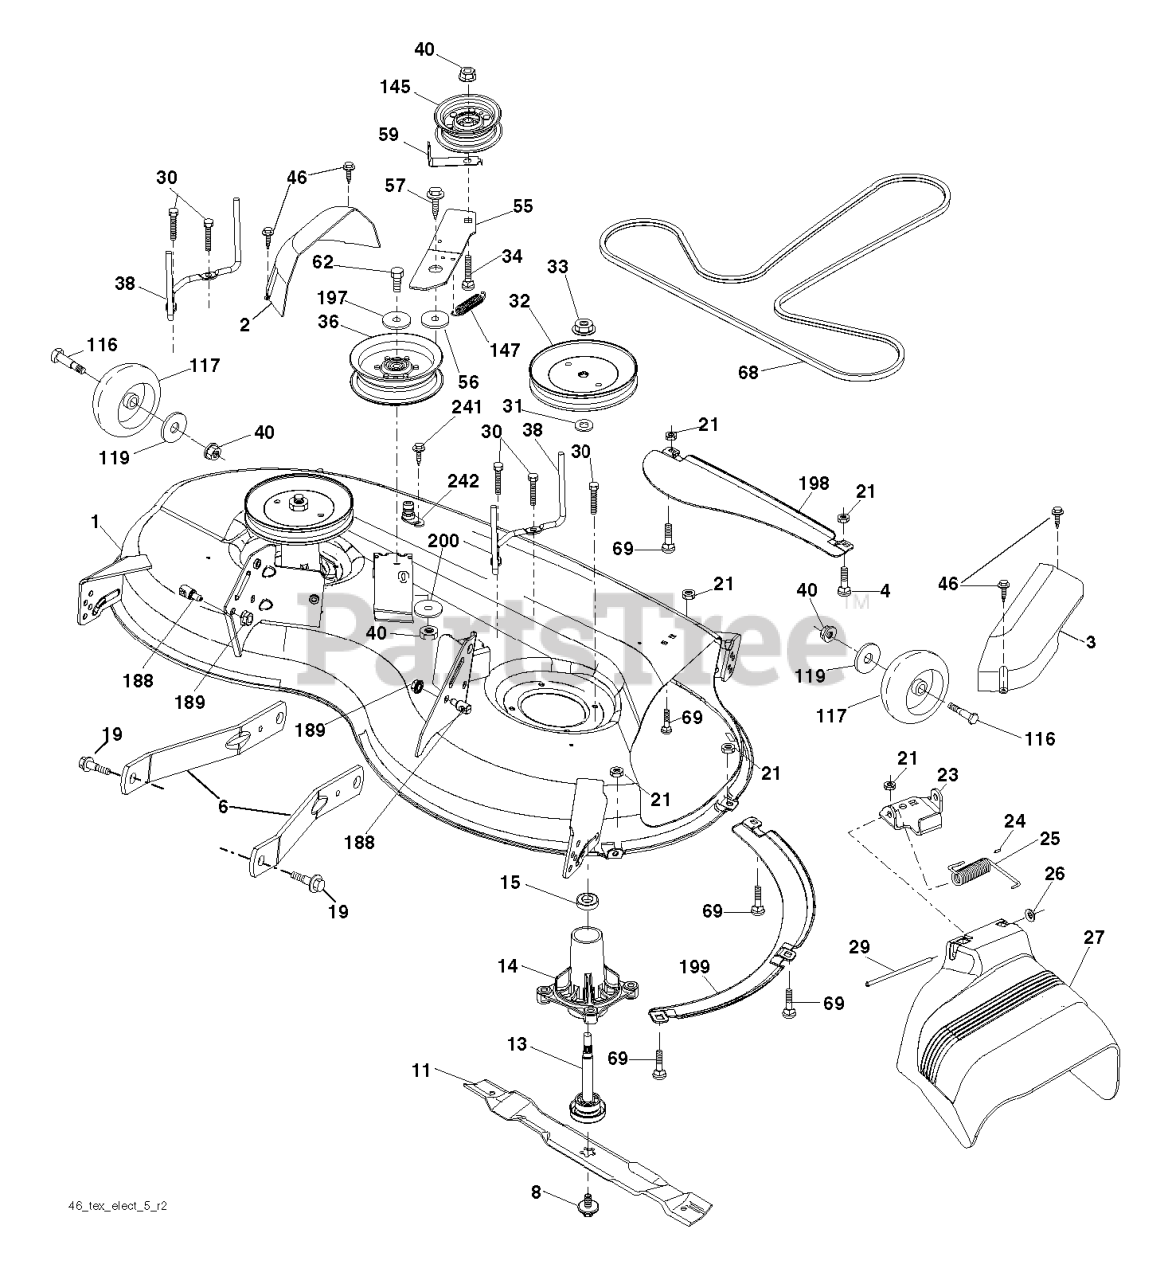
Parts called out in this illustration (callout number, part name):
1	DECK.WELDMENT.46.2GA.WHLS.GRAY
2	COVER.MANDREL.LH.46"
3	COVER.MANDREL.RH.46"
6	ARM.SUSPENSION.MOWER.R
8	BOLT.WASHER.ASM.7/16-2
11	BLADE.MOWER.46".HI.LIFT
13	SHAFT.ASM.MDRL.N/GREASE.38
14	RP.HOUSING.MANDREL.4PT.
19	BOLT.SHOULDER
21	LOCKNUT
23	BRKT.DEFLECTOR.38"2005+
24	CAP-SLEEVE LT
25	SPRING.TORSION.DEFLECT
26	NUT PUSH M
27	SHIELD.DEFLECTOR.MOWER.46"BLAC
29	ROD.HINGE
30	SCREW, WASHER HEAD
31	WASHER.SPACER.MANDREL
32	PULLEY.MANDREL.5.438.PD
33	NUT.FLANGE.LOCK.TOP
34	BOLT.3/8-16X1.50
36	PULLEY.IDLER.2006
38	KEEPER.BELT.MANDREL.PULLEY
40	NUT LOCK FLG 3/8-16 UNC
46	SCREW.1/4-20X5/8
55	IDLER.ARM
56	SPACER.RETAINER
57	SCREW 3/8-16X1
59	GUARD, BELT
62	BOLT-HEX EAK
68	V-BELT
69	BOLT
116	BOLT M
117	WHEEL.GAGE.HALF.SPOKED
118	LOCKNUT
119	WASHER.5/16.FLAT.STE.STD.
145	PULLEY.IDLER.48"PRIMARY
147	SPRING.MOWER.DRIVE.ELECTRIC
188	STUD.FASTNER.W/ANTI-ROTATE
189	NUT LOCK HEX FLANGE 5/16-18
197	WASHER
198	BAFFLE CENTER FRONT
199	BAFFLE FRONT RH
200	WASHER.13/32 X 1 X 1/2.11GUARD
241	SCREW.TT.#10-32X.5.3/8.FLANGE
242	PORT.WASHOUT
